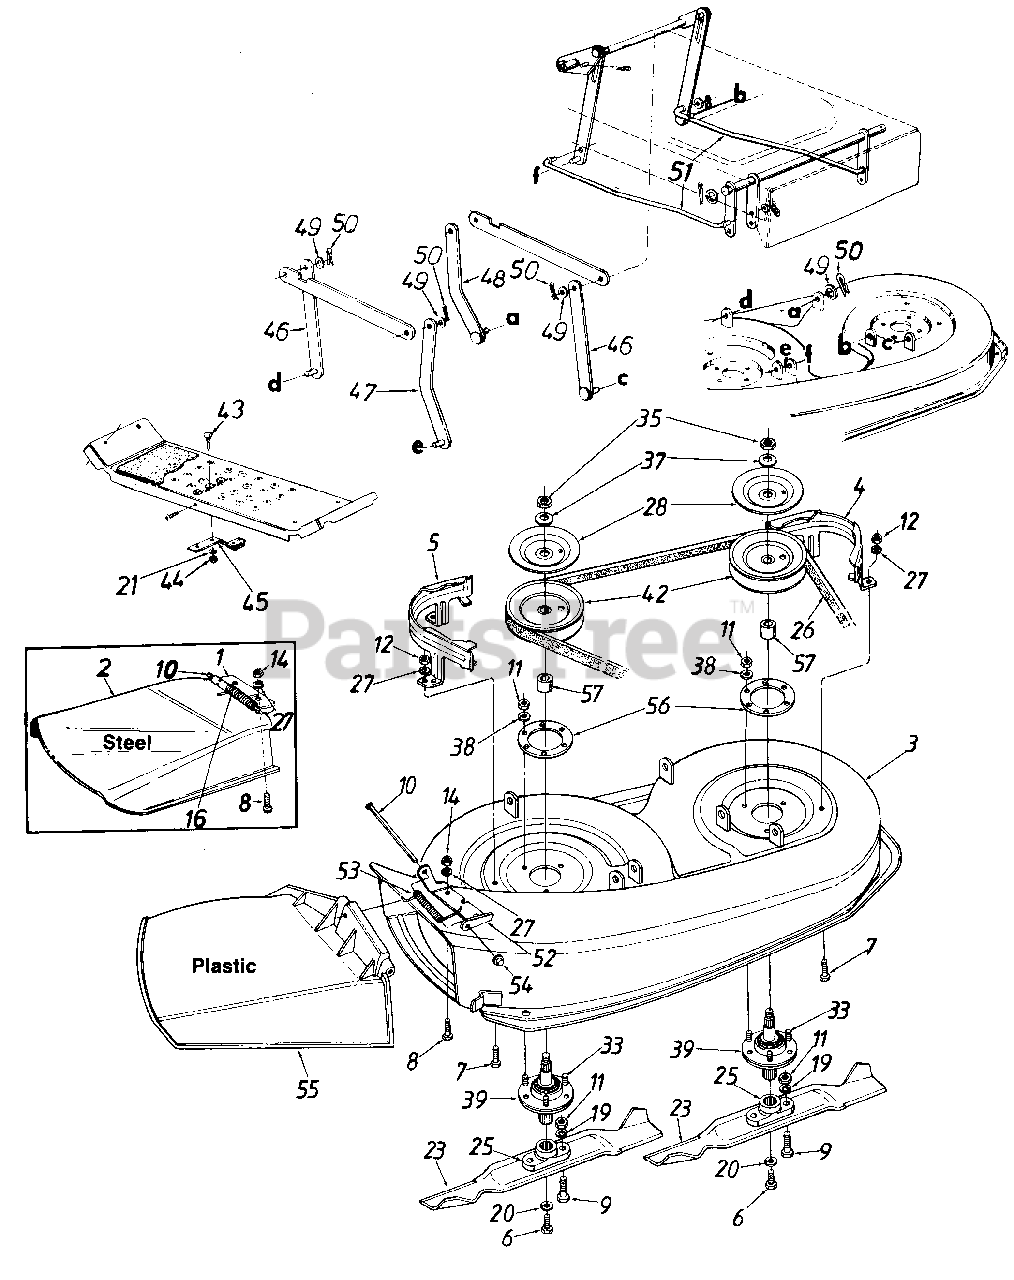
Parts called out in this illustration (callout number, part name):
1	Chute Bracket (Steel)
2	Chute Deflector (Steel)
3	36" Deep Deck Ass'y.
7	Hex Bolt 1/4-28 x .62"
8	Truss Mach. Scr. 1/4-20 x .75"
9	Hex Bolt Special 5/16-24 x 1.0"
10	Hinge Pin
11	Hex Nut 5/16-24 Thd.
12	Hex Nut 1/4-28 Thd.
14	Hex Jam Nut 1/4-20 Thd.
16	Torsion Spring
19	L-Wash. 5/16" I.D.
20	L-Wash. 3/8" I.D.-H.D.
21	L-Wash. 1/4" I.D.
23	High-Lift Blade
25	Blade Adapter
26	5L V-Belt
27	Bell-Wash. 1/4" I.D.
28	Brake Disc
33	Rib Neck Bolt 5/16-24 x .84" Lg.
35	Hex Jam Nut 5/8-18 Thd.
37	L-Wash. 5/8" I.D.
38	L-Wash. 5/16" I.D.
39	Blade Spindle Ass'y. Comp.
42	5" Dia. Pulley
43	Carr. Bolt 1/4-20 x .62"
44	Hex Nut 1/4-20 Thd.
45	Blade Brake Ass'y.
46	Link Deck Hanger Ass'y.
47	Link Deck Hanger Ass'y.
50	Inter. Cotter Pin .50" Dia.
51	Stabilizer Rod
52	Hinge Mtg. Brkt.
53	Torsion Spring
54	Push Nut
55	Chute Ass'y. Comp. (Plastic)
56	Reinforcement Plate
57	Spacer
